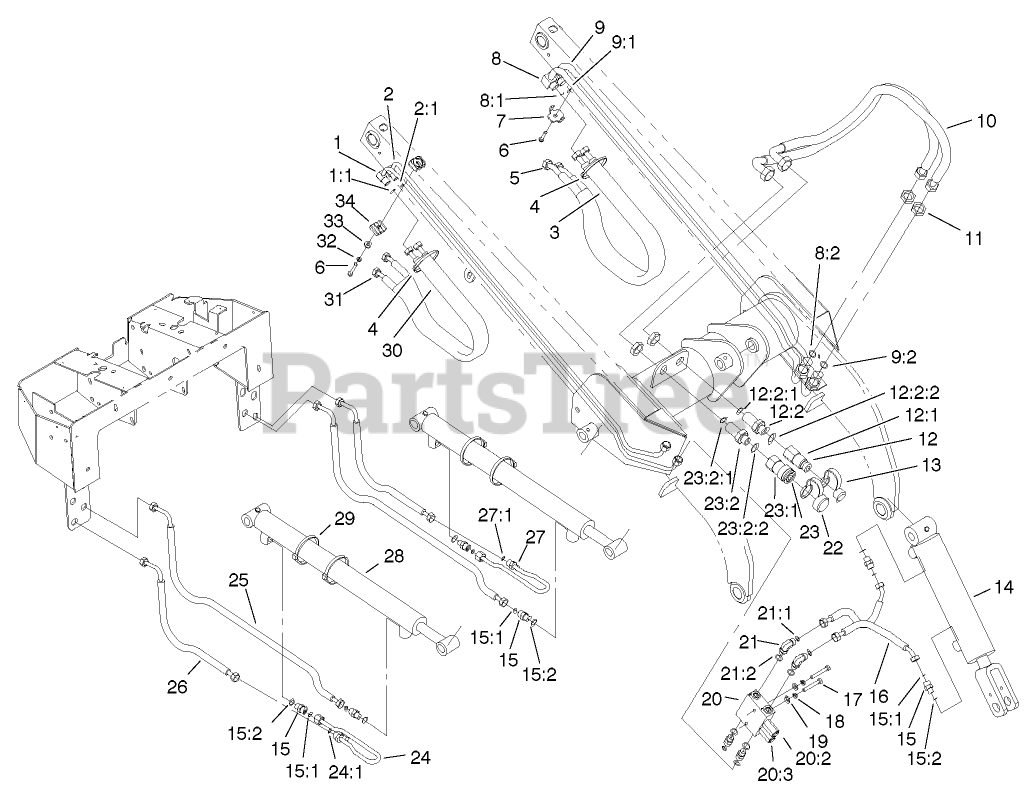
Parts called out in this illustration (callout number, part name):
1	HYD TUBE ASM
1:1	O-RING
2	HYD TUBE ASM
2:1	O-RING
3	SLEEVE-PROTECTIVE
4	TIE-CABLE
5	HOSE-HYD
6	SCREW-HWH
7	PLATE-CLAMP, TUBE
8	HYD TUBE ASM
8:1	O-RING
8:2	O-RING
9	HYD TUBE ASM
9:1	O-RING
9:2	O-RING
10	HOSE ASM
11	NUT-LOCK, BULKHEAD
12	BULKHEAD NIPPLE ASM
12:1	NIPPLE-FACE, FLUSH
12:2	FITTING-ADAPTER, BULKHEAD
12:2:1	O-RING
12:2:2	O-RING
13	CAP-DUST, NIPPLE
14	CYLINDER-TILT
15	FITTING-STRAIGHT
15:1	O-RING
15:2	O-RING
16	HOSE-HYD
17	SCREW-HH
18	WASHER-LOCK
19	WASHER-PLAIN
20	VALVE-RELIEF, CROSSOVER
20:2	CARTRIDGE-RELIEF
20:3	CARTRIDGE-RELIEF
21	FITTING-ELBOW, 90 DEG
21:1	O-RING
21:2	O-RING
22	CAP-DUST, COUPLER
23	BULKHEAD COUPLER ASM
23:1	COUPLER-FACE, FLUSH
23:2	FITTING-ADAPTER, BULKHEAD
23:2:1	O-RING
23:2:2	O-RING
24	HYD TUBE ASM
24:1	O-RING
25	HYD HOSE ASM
26	HOSE-HYD
27	HYD TUBE ASM
27:1	O-RING
28	CYLINDER-LIFT
29	TIE-CABLE
30	SLEEVE-PROTECTIVE
31	HOSE-HYD
32	WASHER-LOCK
33	WASHER-FLAT
34	CLAMP-TUBE
